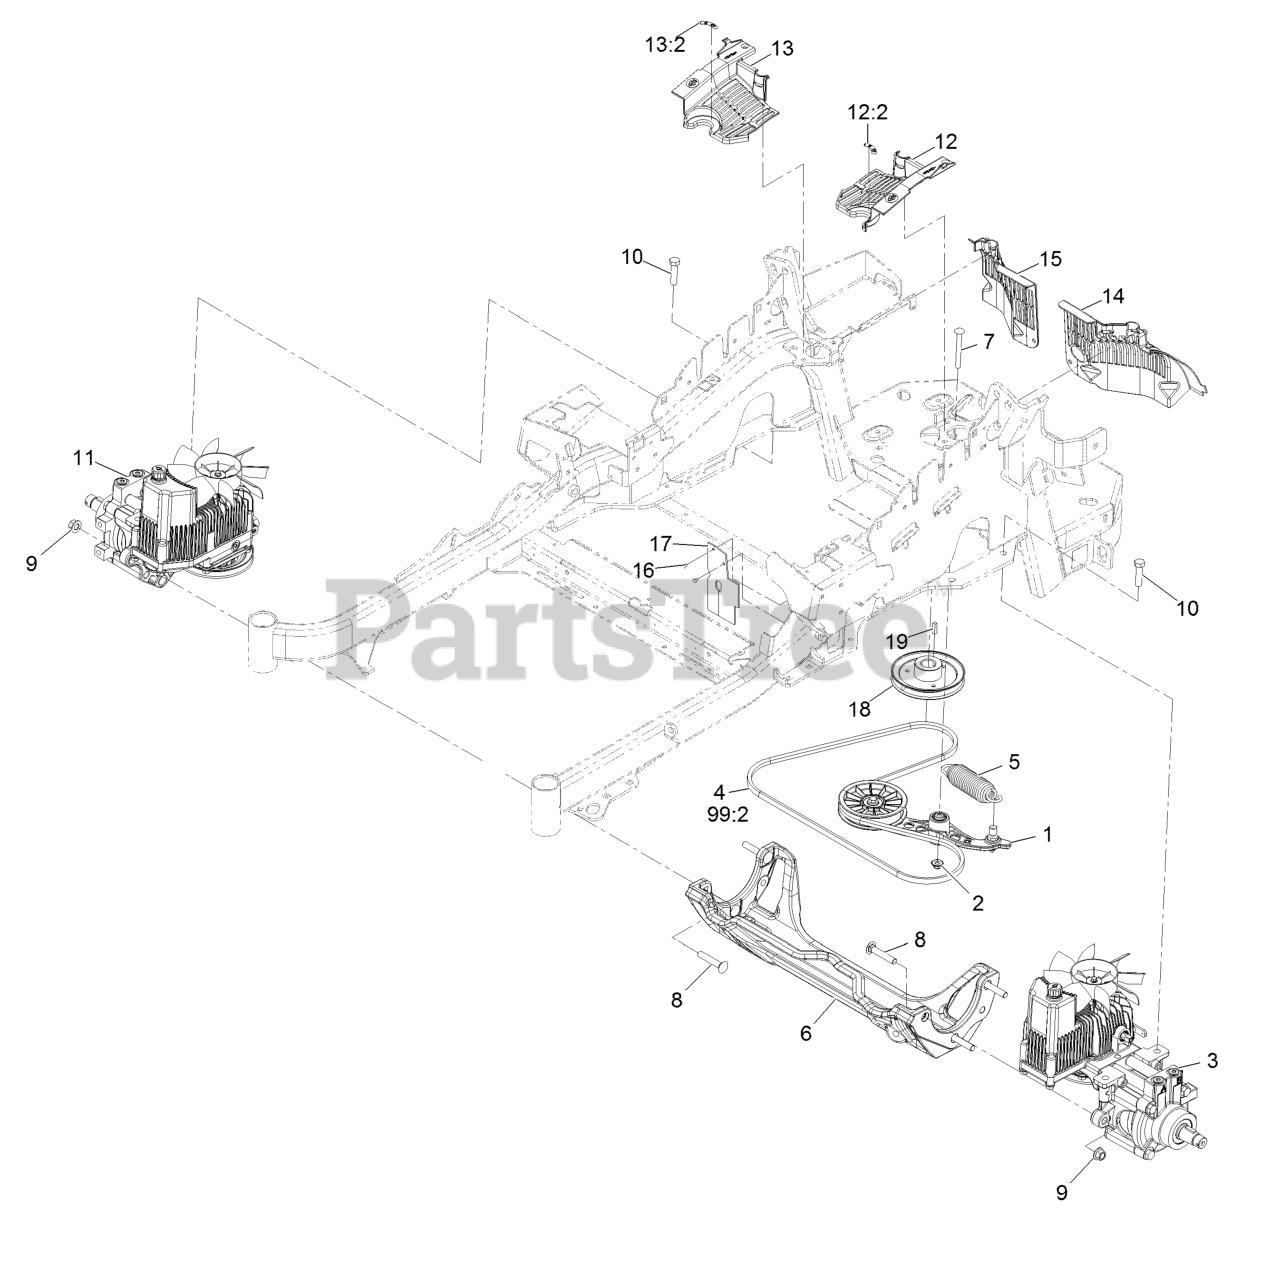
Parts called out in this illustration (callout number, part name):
1	PUMP IDLER ASM
2	Nut-Nyloc 3/8-16 Flg
3	LH HYDRO ASM (12CC W/ CHECK)
4	BELT
5	SPRING-EXTENSION
6	CRADLE-HYDRO
7	BOLT-SHOULDER, CARRIAGE 3/8-16 X 3 1/2
8	SCREW-CARR
9	Nut-Lock 1/2-13
10	SCREW-HH
11	RH HYDRO ASM (12CC W/ CHECK)
12	LH HYDRO GUARD ASM
12:2	DECAL-OIL, HYDRO
13	RH HYDRO GUARD ASM
13:2	DECAL-OIL, HYDRO
14	GUARD-HYDRO, REAR (LH)
15	GUARD-HYDRO, REAR (RH)
16	RIVET-POP
17	DEFLECTOR-AIR FLOW
18	SHEAVE
99:2	BELT
